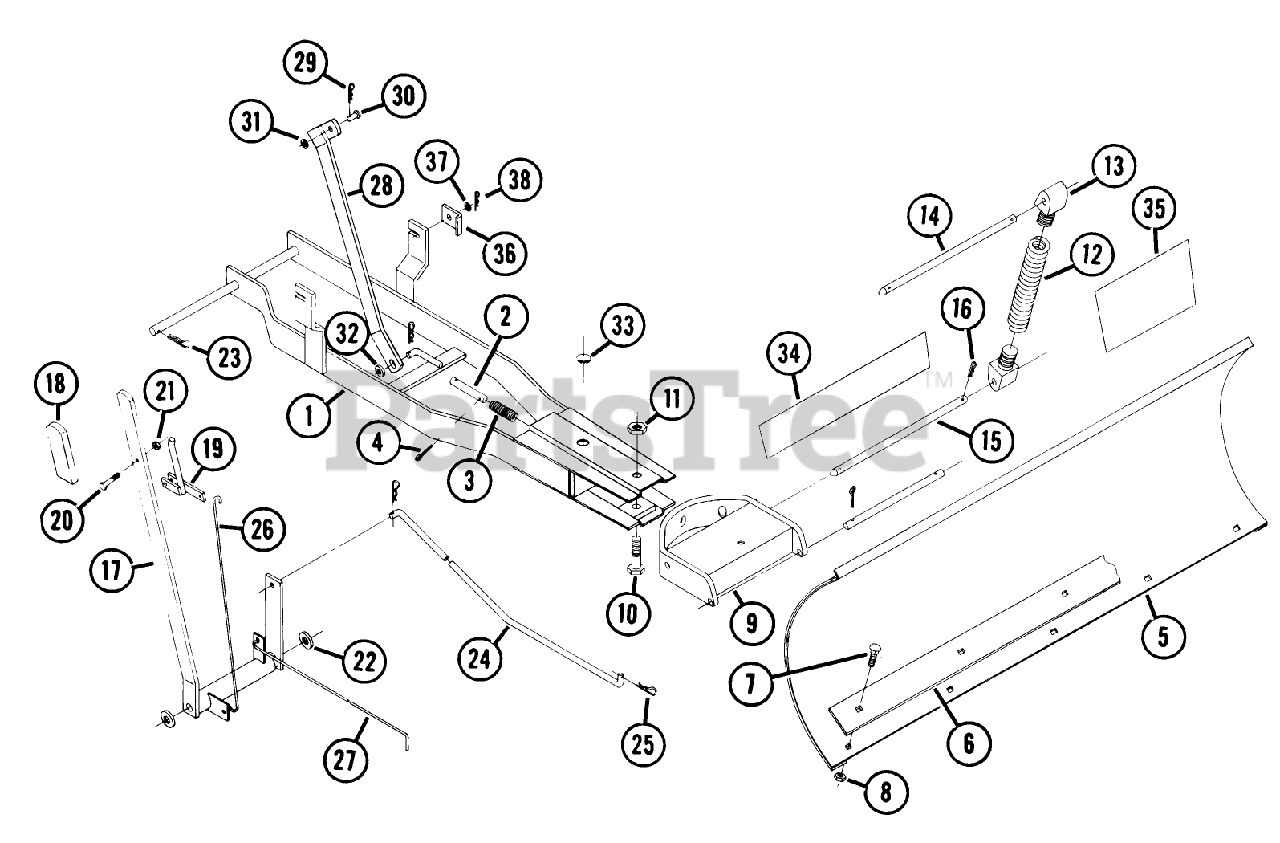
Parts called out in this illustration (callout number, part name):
3	SPRING-COMPRESSION
5	ORD 109593 & 109596
14	ROD-PIVOT, BLADE
15	ROD-LOWER
16	Hairpin
18	GRIP
23	Hairpin
25	Hairpin
29	Hairpin Cotter
33	PLUG
38	Hairpin Cotter
